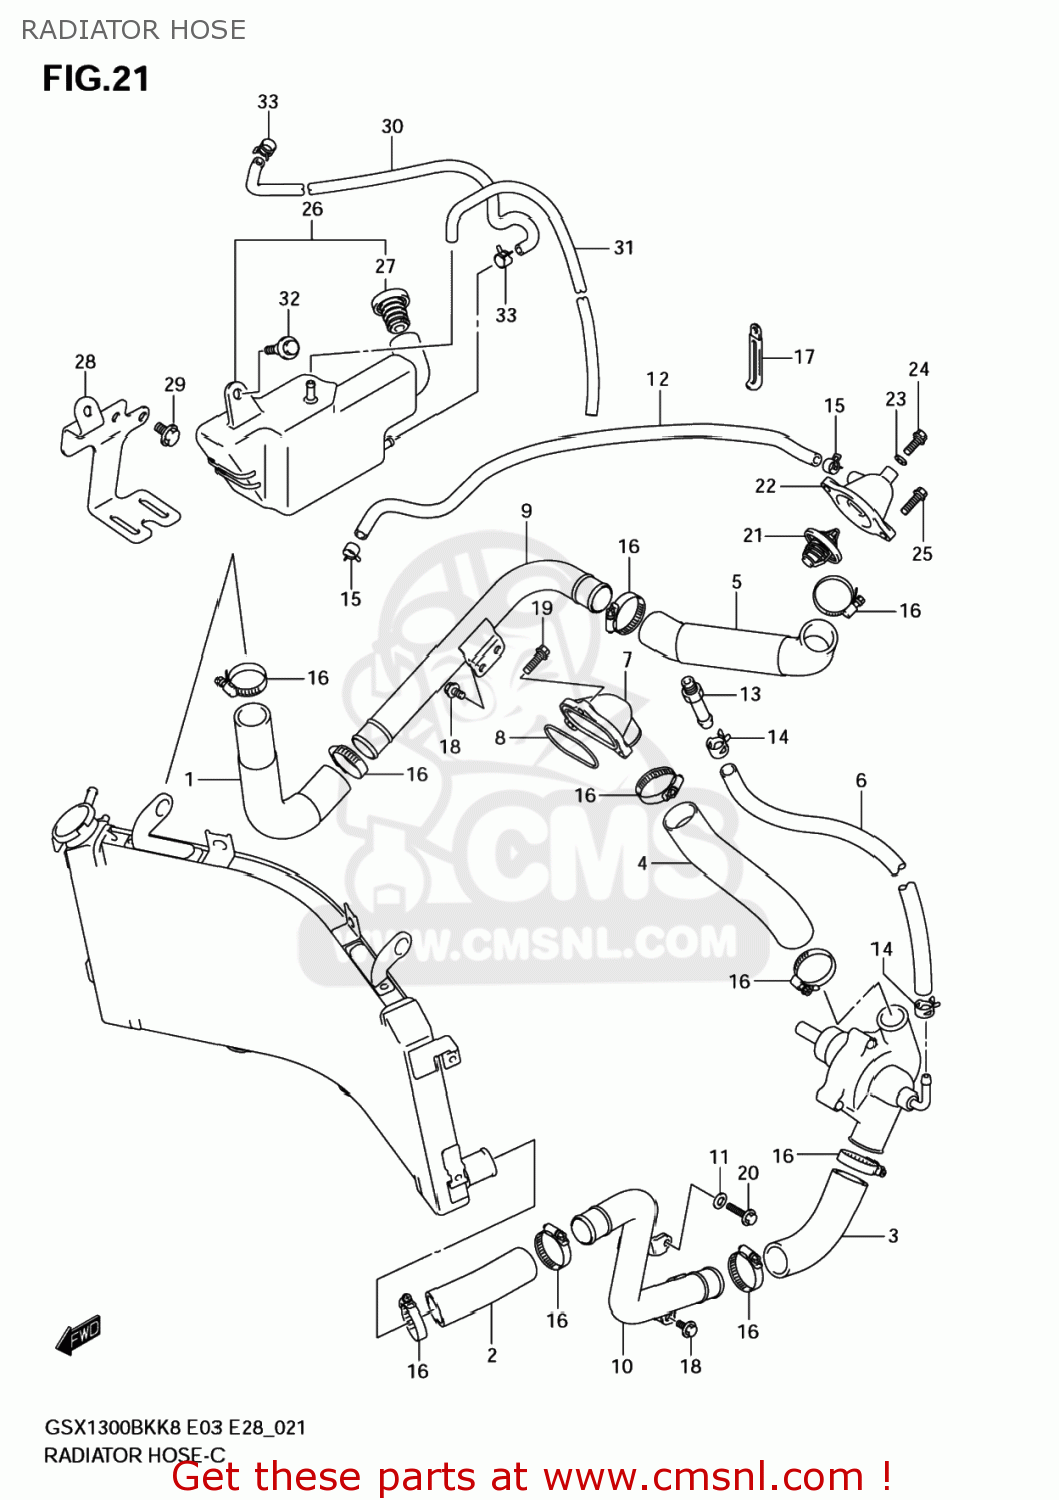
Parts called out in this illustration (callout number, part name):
1	HOSE,RADIATOR INLET
2	HOSE,RADIATOR OUTLET
3	HOSE,WATER PUMP INLET
4	HOSE,CYLINDERL INLET
5	HOSE,CYLINDER HEAD OUTLET
6	HOSE,WATER BYPASS NO.1
7	CONNECTOR,CYLINDER WATER INLET
8	O RING,CYL WATER CONNECTOR
9	PIPE,RADIATOR INLET
10	PIPE,RADIATOR OUTLET
11	WASHER(6.5X18X1.6)
12	HOSE(5X11X600)
13	BOLT UNION
14	CLAMP
15	CLIP
16	CLAMP
17	CLAMP(L:80)
18	BOLT
19	BOLT
20	BOLT
21	THERMOSTAT,WATER
22	COVER,THERMOSTAT
23	GASKET(6.4X11.5X0.8) (NAS)
24	UNION BOLT,AIR VENT
25	BOLT
26	TANK ASSY,RESERVOIR
27	CAP,RESERVOIR TANK
28	BRACKET,RESERVOIR TANK
29	BOLT
30	HOSE,RESERVOIR TANK INLET
31	HOSE,RESERVOIR TANK OVFL
32	BOLT(6X12)
33	CLIP
